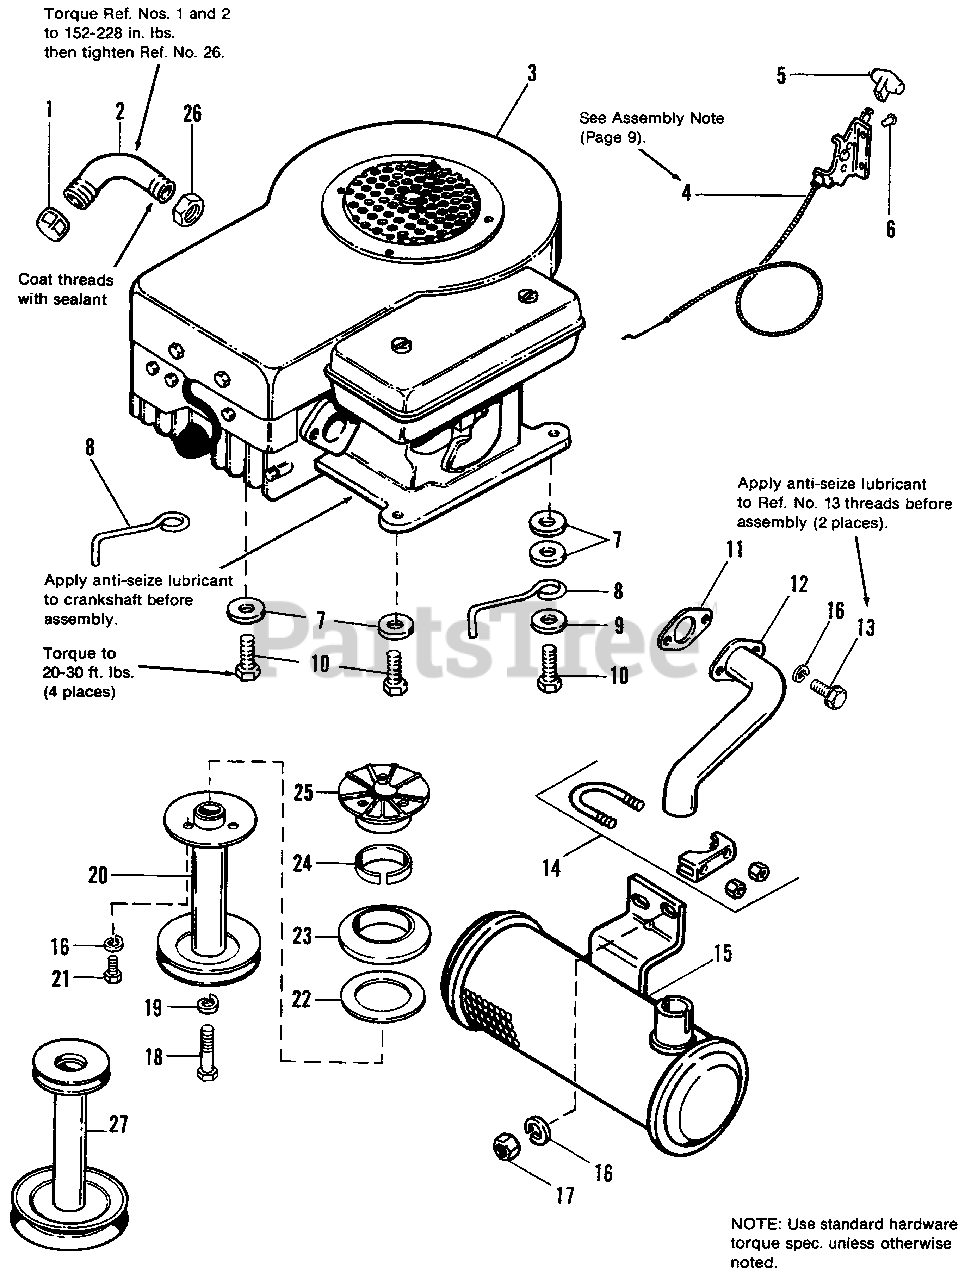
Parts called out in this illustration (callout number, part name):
1	PIPE, Cap, Hex
2	PIPE, Oil Drain (Includes Ref. No. 1, 2 & 26)
4	THROTTLE CONTROL ASSY.
5	KNOB, Throttle
6	RIVET, Pop, 1/4 x .44
7	WASHER, Plain, 13/32
8	STOP, Belt, Engine
9	WASHER, Plain, 3/8
10	SCREW, Taptite, 3/8-16 x 1-1/2
11	GASKET, Muffler
12	PIPE, Exhaust
13	CAPSCREW, Hex, 5/16-18 x 3/4
14	CLAMP, Exhaust
16	LOCKWASHER, 5/16
17	NUT, Hex, 5/16-18
18	CAPSCREW, 7/16-20 x 1-1/4
19	LOCKWASHER, 7/16
20	PULLEY ASSY., Engine
21	CAPSCREW, Socket Hd., 5/16-18 x 3/4
22	BEARING
23	PULLEY, Half, Lower
24	BEARING
25	PULLEY, Half, Upper
26	LOCKNUT, Conduit, 3/8
27	PULLEY ASSY., Engine
